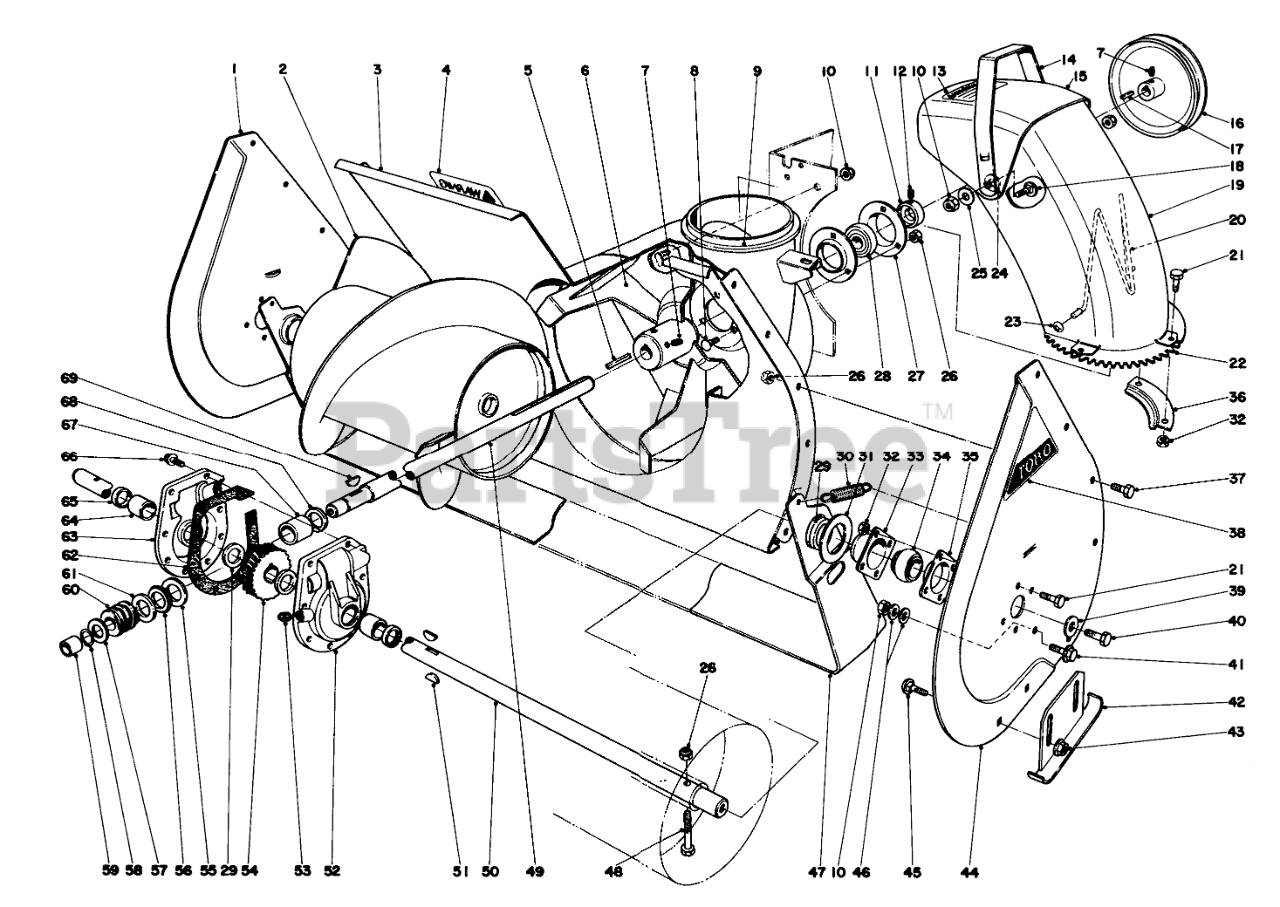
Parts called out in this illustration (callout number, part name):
1	Side Plate Right
2	Auger R.H.
3	Auger Housing
4	Decal
6	IMPELLER WA RO
7	SCREW-SET, SQH
8	BOLT-CARR
9	SUPPORT B
10	NUT-LOCK, CONE
11	EXT LOCKING COLLAR
12	SCREW-HSH
13	CHUTE WARNING DECAL
14	DEFLECTOR HANDLE B
15	Chute Deflector
16	IMPELLER PULLEY
17	SQUARE KEY
18	SCREW-CARR
19	Chute
20	WIRE-CHUTE
21	SCREW-HH
22	Chute Swivel Gear
23	NUT-PUSH
24	WASHER-RUBBER
25	WASHER-BELLEVILLE
26	NUT-LOCK, CONE
27	BRG FLANGE
28	BALL BRG W/COLLAR
29	WASHER-THRUST
30	SPRING-TENSION
31	SCRAPER BLADE SPACER
32	NUT-LOCK, CONE
33	BEARING-FLANGE, REAR
34	BEARING
35	BEARING-FLANGE, FRONT
36	CHUTE RETAINER
37	SCREW-HH
38	AUGER SIDE PLT DECAL
39	WASHER
40	SCREW-HH
41	SCREW-HHF
42	Skid
43	NUT-HHF, WHIZ
44	Sideplate Auger Left
45	SCREW-CARR
46	WASHER-FLAT
47	Scraper Blade
48	Auger Bolt
49	Impeller Shaft
50	24 AUGER SHAFT
51	KEY-WOODRUFF
52	Gear Case Left Half (Incl. Ref. #64-65)
53	PLUG-PIPE, SQH
54	GEAR-WORM, 27T
55	WASHER-THRUST
56	BEARING-THRUST
57	WASHER-THRUST
58	Ring-Snap
59	BUSHING
61	THRUST-WASHER
62	Gasket
63	Gear Case Right Half (Incl. Ref. #64-65)
64	BUSHING
65	SEAL-OIL
66	SCREW-HWHTF
67	BUSHING-SPECIAL
68	RING-QUAD
69	KEY-WOODRUFF
